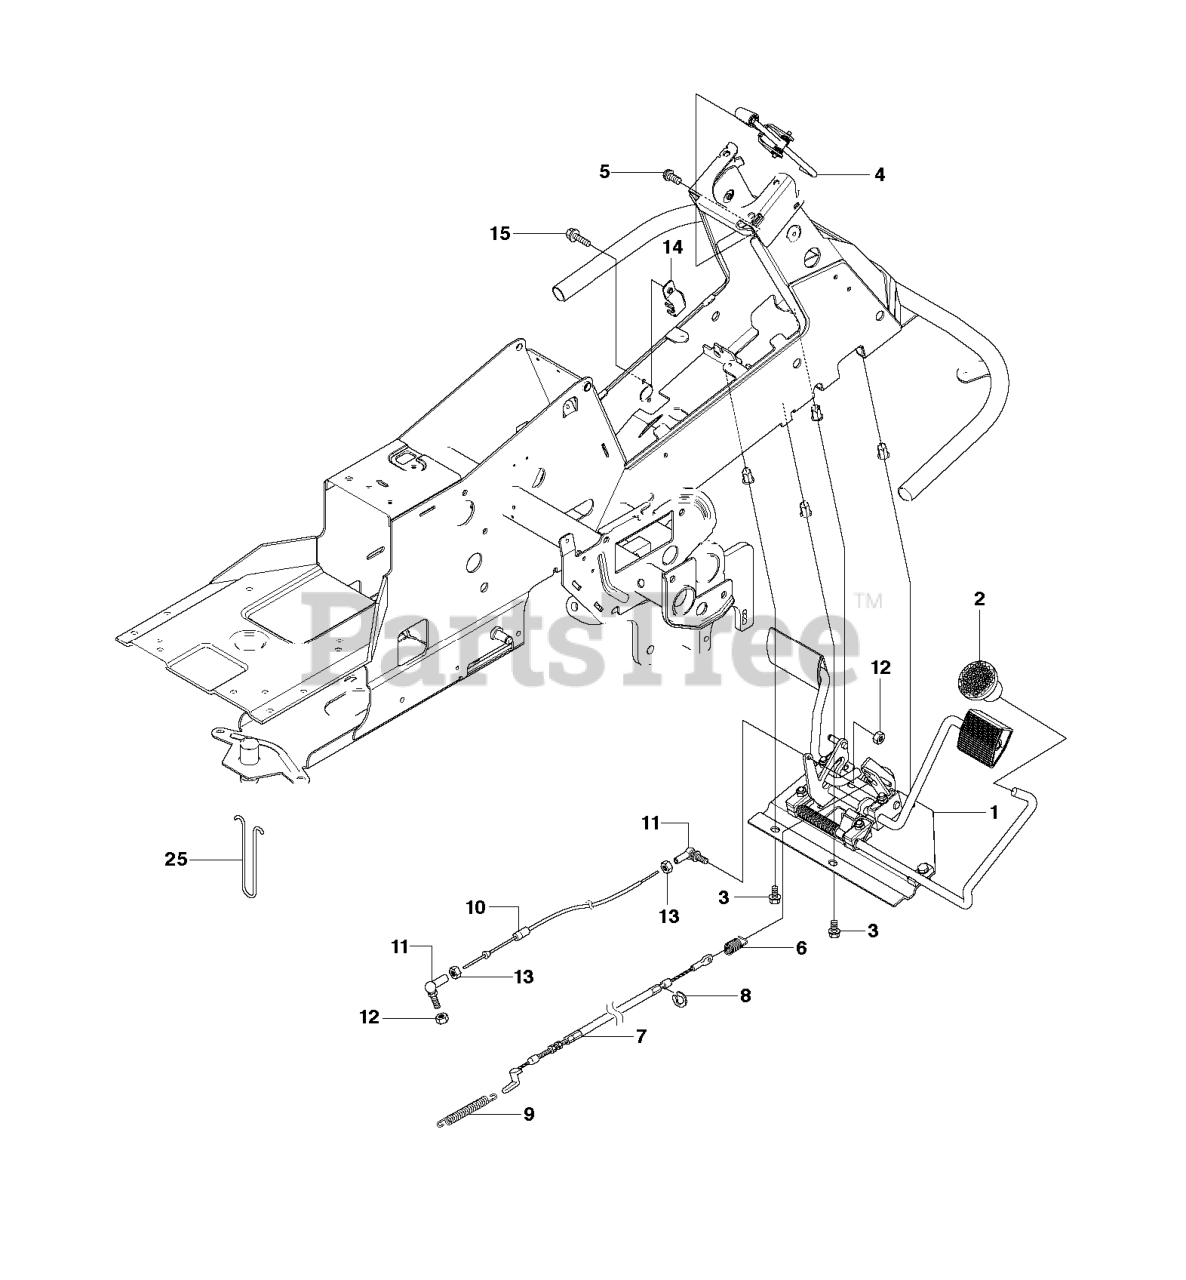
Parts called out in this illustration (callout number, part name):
1	PEDAL ASSEMBLY
2	KNOB
4	BRAKE LEVER ASSY
7	RP WIRE
10	CONTROL CABLE
11	CONNECTOR
12	LOCKNUT M5
25	CABLE HOLDER
